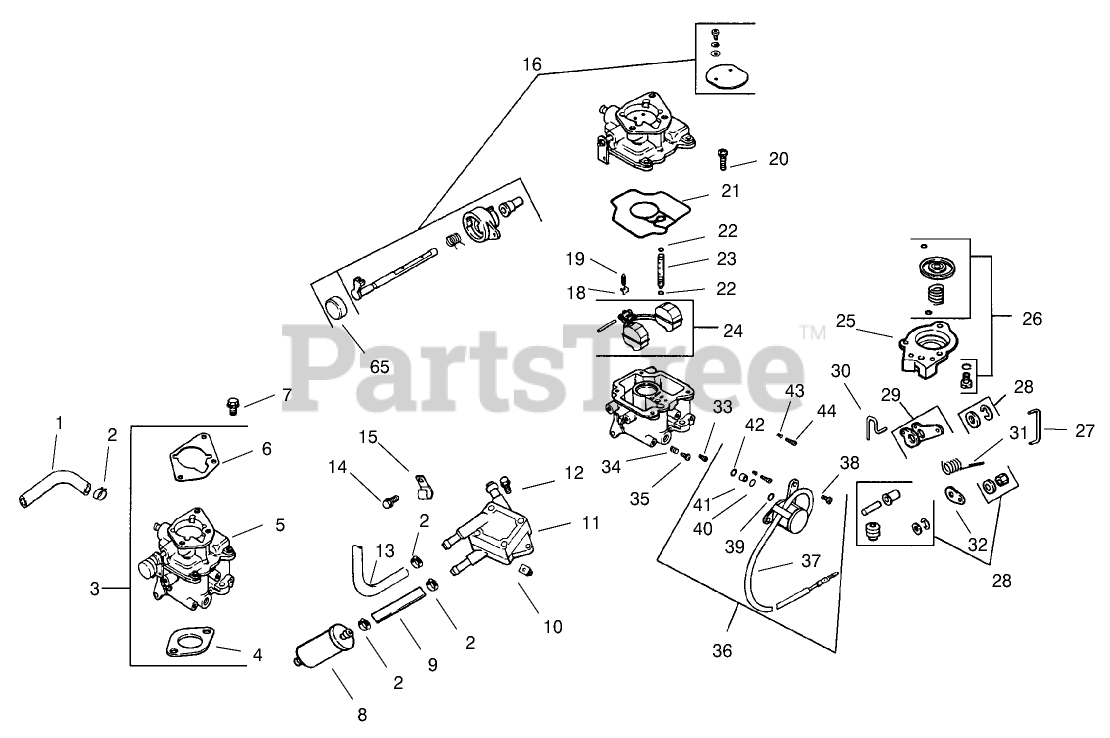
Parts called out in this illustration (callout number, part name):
1	Line fuel
2	Clamp
3	Kit-Carburetor(Incl. Ref.# 4-6)
4	Gasket
5	Carburetor ASM
6	Gasket
7	Screw
8	Filter-Fuel
9	Line-Fuel
10	Nut
11	Pump-Fuel
12	Screw
13	Line, fuel
14	Screw
15	Clamp
18	Clip, cable
19	Valve-Inlet Needle
20	Screw
21	Gasket-Body,Carburetor
22	"O"Ring
23	Jet-Slow
24	Roat Repair Kit
25	Housing-Pump
26	Kit repair-accelerator pump
27	Linkage-Rod
28	Kit repair-accelerator pump diagram
29	Lever-Rod
30	Linkage-Rod
31	Spring-Linkage
32	Lever-Linkage
33	Jet-Main
34	Screw, idle adjusting
35	Spring-Idle Speed Adj.
36	Solenoid ASM Kit(Incl. Ref.# 37-42)
37	O-Ring
38	Seat-Solenoid
39	O-Ring
40	O-Ring
41	Solenoid
42	Screw
43	Spring-Idle Adj.
44	Needle, idle
